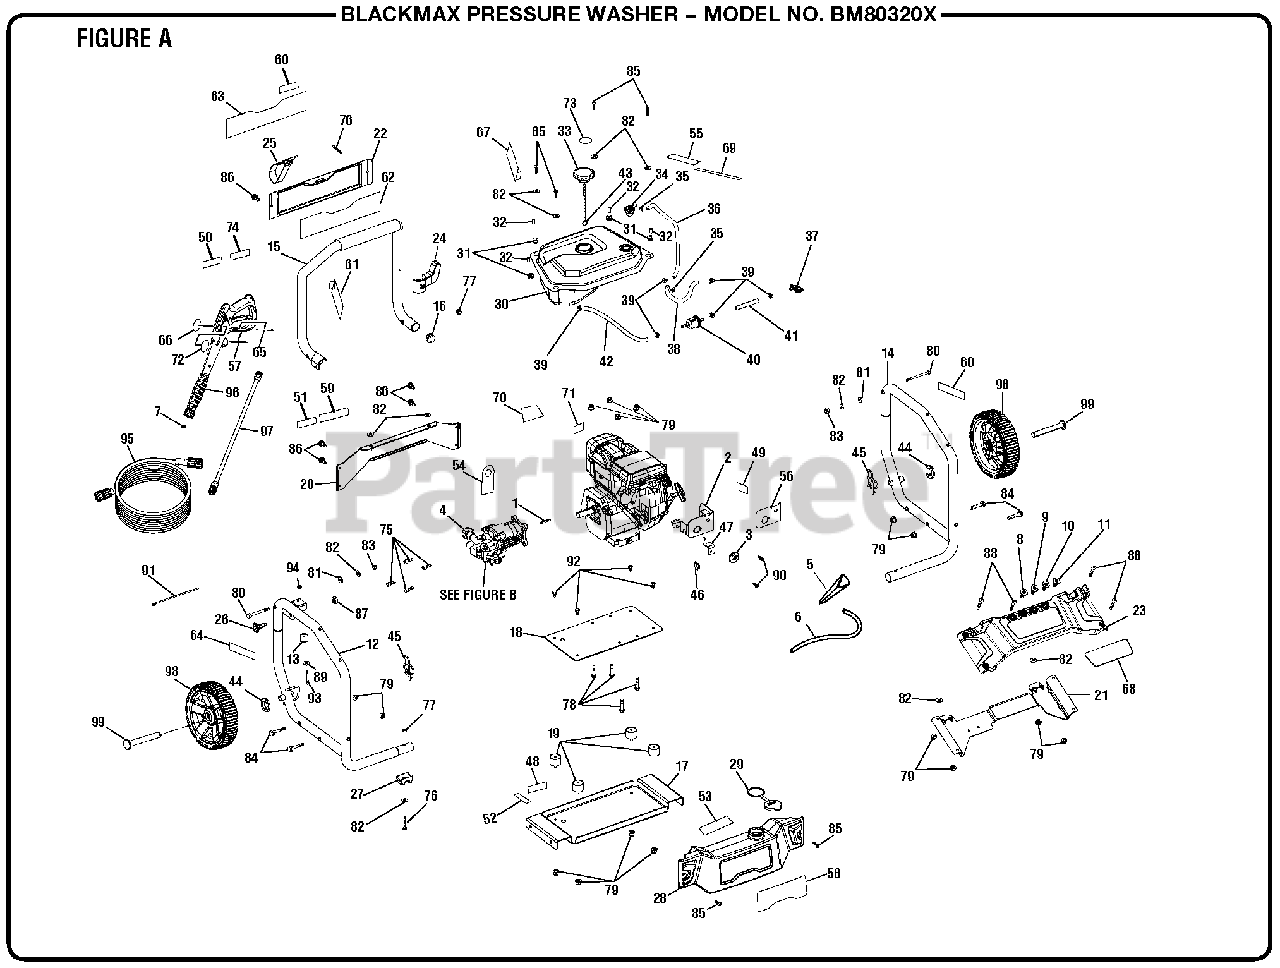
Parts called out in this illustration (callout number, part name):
1	Output Shaft Key
2	Fuel Valve Bracket
3	Fuel Valve Bezel
6	Chemical Siphon Tube
8	0deg Nozzle
9	25deg Nozzle
10	40deg Nozzle
11	Soap Nozzle (Blue)
12	Main Frame Assembly (Left)
13	Rubber Bumper
14	Main Frame Assembly (Right)
15	Handle Assembly
17	Engine Plate
18	Spacer Plate
20	Fuel Tank Support (Rear)
21	Fuel Tank Support (Front)
22	Hose Holder Panel
23	Faceplate Panel
24	Upper Wand Holder
25	Hose Holder Strap
26	Handle Lock Assembly
28	Soap Tank
29	Soap Tank Cap
30	Fuel Tank Assembly
31	Fuel Tank Bushing
32	Fuel Tank Bushing Insert
34	Vapor Vent
35	Hose Clamp (3/8 in.)
36	Vapor Hose (550 mm)
37	Fuel Valve
38	Fuel Hose (245 mm)
39	Hose Clamp (1/2 in.)
40	Fuel Filter
41	Fuel Hose (90 mm)
42	Fuel Hose (265 mm)
43	Ring Clip
44	Washer (1/2 in.)
45	Wheel Axle Ring Clip
46	Vapor Adapter
47	Vapor Adapter Bracket
48	Add Oil Label
49	Choke & Engine Switch Label
50	Combustion Label (English/Spanish)
51	Danger Label
52	Data Warnings Label (English/Spanish)
53	Soap Dilution Label
54	Oil Dipstick Hangtag
55	E85 Label
56	Fuel Valve Label
57	Trigger Handle Rating Label
58	Soap Tank Label
59	Hot Surface & Exhaust Label
60	Inquiries Label
61	Standard Nozzle Hangtag
62	Performance Label
63	Quick Start Label
64	Handle Release Label
65	Trigger Handle Warning Label (French/Spanish)
66	Black Max Wand Logo Label
67	Danger Hangtag
68	Black Max Logo Label
69	Extended Run Label
70	GC190 Label
71	Not For Sale In Ca Label
72	Trigger Handle Warning Label (English)
73	Remove Cap Fuel Stabilizer Label (English)
74	Remove Cap Fuel Stabilizer Label (Spanish)
75	Screw (5/16-24 x 23 mm, Cap Soc. Hd.)
76	Bolt (M6 x 48 mm, T30 Torx Pan Hd.)
77	Lock Nut (M6)
78	Bolt (M8 x 40 mm, Flange Hex Hd.)
79	Lock Nut (M8)
80	Connection Pin
82	Washer (1/4 in.)
83	Lock Nut (1/4-20 in.)
84	Bolt (M8 x 55 mm, Flange Hex Hd.)
85	Bolt (M6 x 25 mm,T30 Torx Pan Hd.)
86	Bolt (M6 x 16 mm, Flange Hex Hd.)
87	Nut (1/2-20 in.)
88	Bolt (M8 x 50 mm, Button Hd.)
89	Washer (M4)
90	Bolt (M6 x 16 mm, Pan Hd.)
92	Bolt (M8 x 15 mm, Hex Hd.)
93	Bolt (M4 x 12 mm, Button Hd.)
94	Lock Nut (M4)
95	Hose (50 Ft.)
96	Trigger Handle
97	Wand Assembly
99	Wheel Axle
